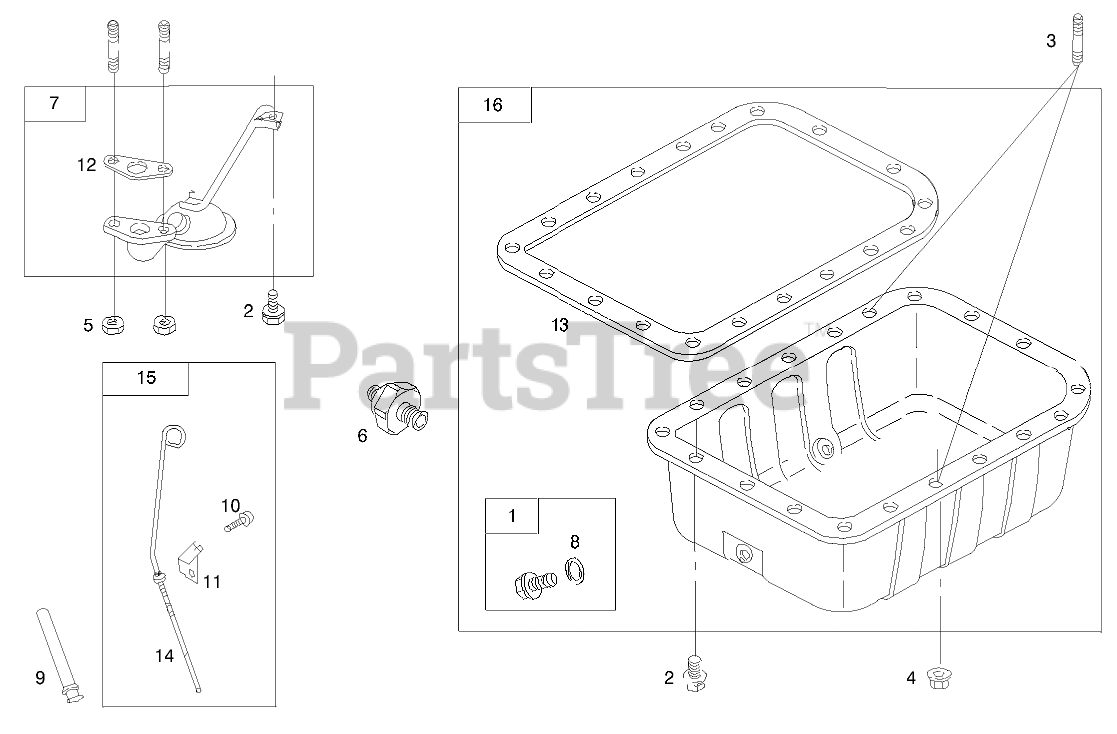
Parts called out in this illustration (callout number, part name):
1	PLUG-DRAIN, OIL
2	SCREW-HEX
3	STUD-METRIC
4	NUT-HEX, METRIC
4	NIPPLE ASM
5	NUT-HEX, METRIC
5	VALVE ASM
6	SWITCH-PRESSURE, OIL
7	SCREEN-PUMP, OIL
8	WASHER-SEAL
9	TUBE-DIPSTICK
9	GASKET-SET
10	SCREW-HEX
11	Bracket-Support
12	GASKET-STRAINER, OIL
13	GASKET-PAN, OIL
14	DIPSTICK
14	VALVE OVERHAUL KIT
15	DIPSTICK
15	SHAFT-GEAR
16	PAN-OIL
